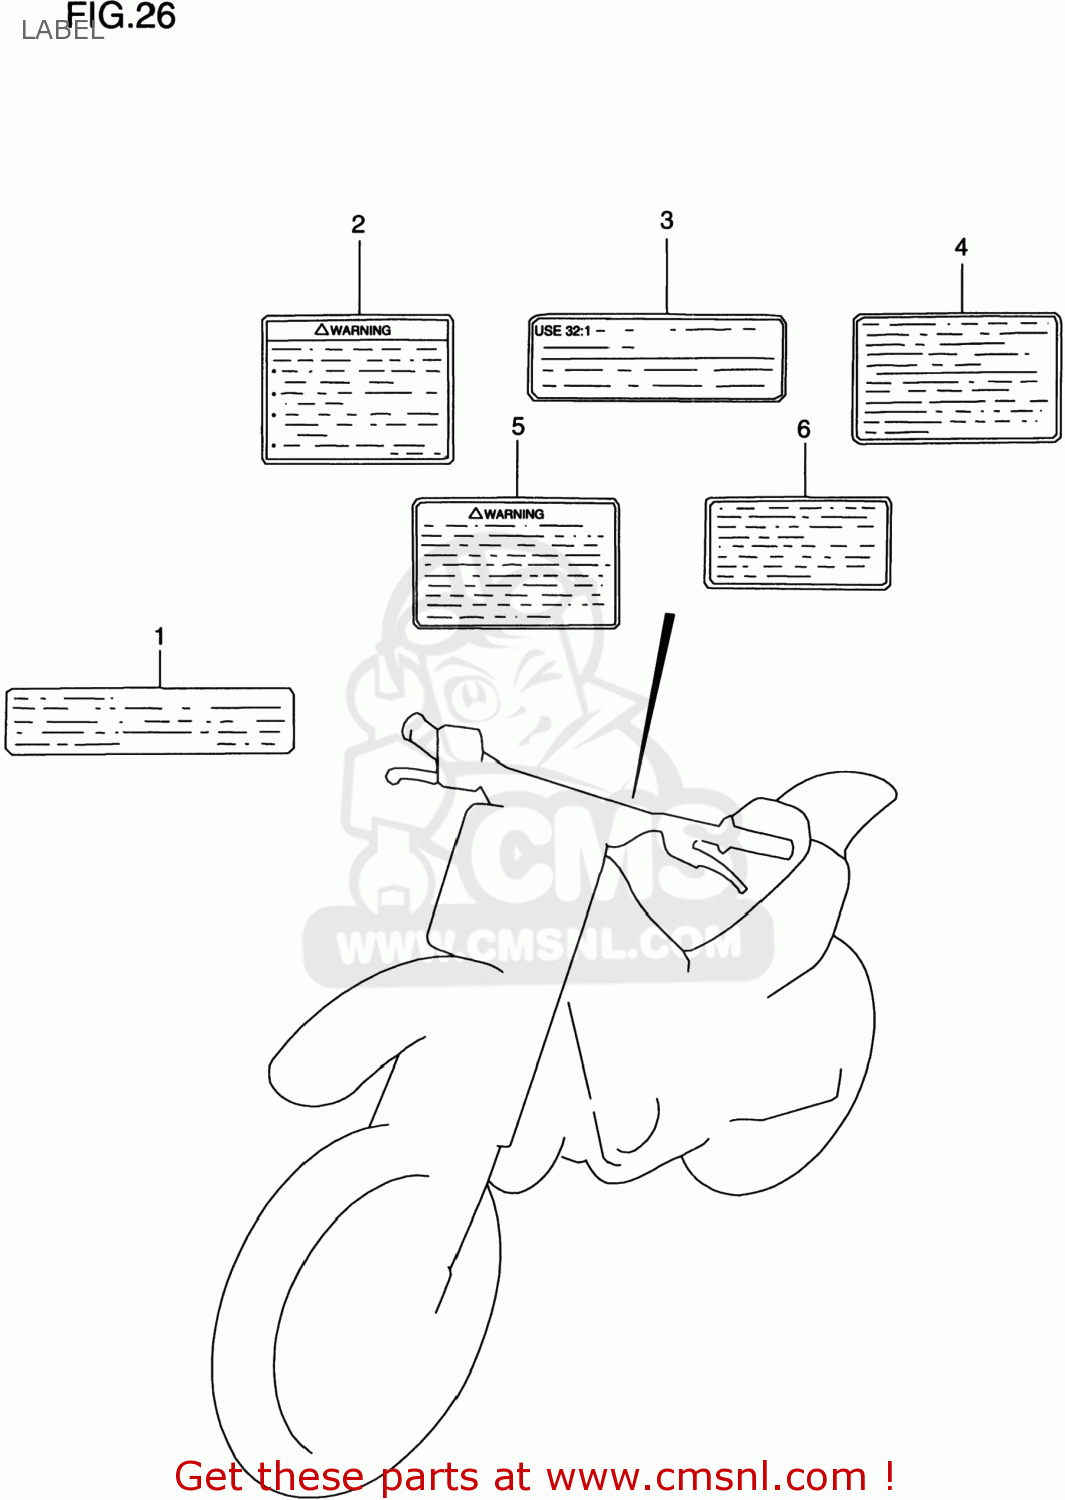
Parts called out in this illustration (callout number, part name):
1	PLATE,WARNING
2	LABEL,GENERAL WARNING
3	LABEL,WARNING NO.2
4	LABEL,WARNING
5	LABEL,WARNING
6	LABEL (MANUAL NOTICE)
7	MANUAL, OWNER'S
